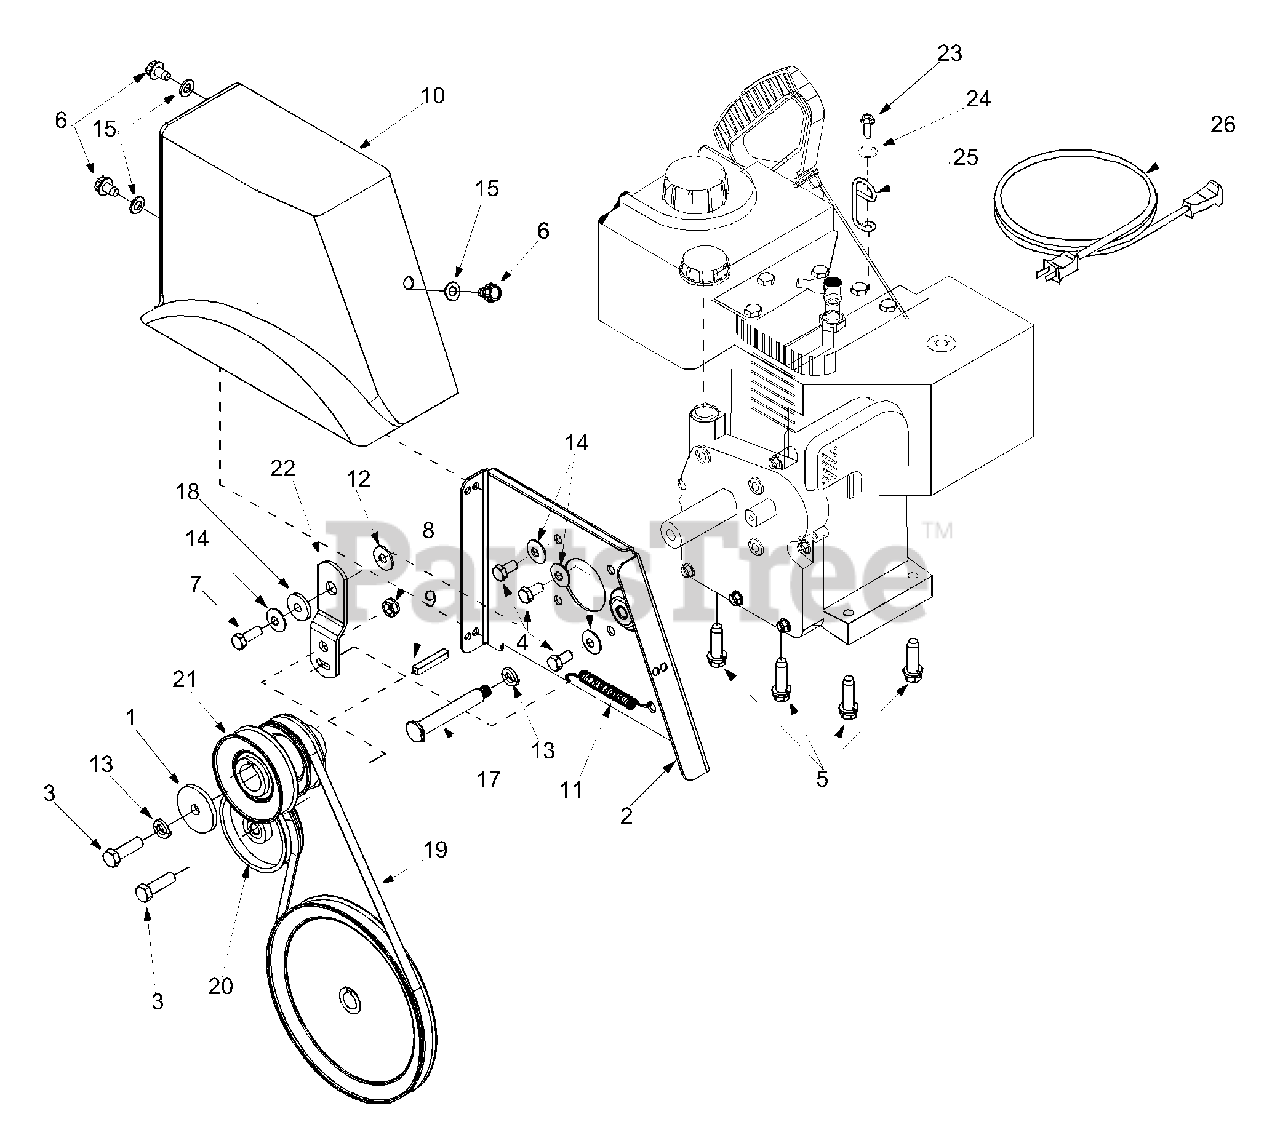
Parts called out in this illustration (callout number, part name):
1	Washer
2	Belt Cover Bracket Assembly
3	Hex Screw 3/8-24 x 1.25"
4	Hex Screw 5/16-24 x .625"
5	TT Sems Screw
6	TT Screw 5/16-18 x 0.5"
7	Hex Lock Screw 5/16-24 x .875"
8	Jam Nut
10	Belt Cover
11	Extension Spring
12	5/16 Washer
13	Lock Washer
14	Beleville Washer
15	Flat Washer
17	Shoulder Screw
18	Shoulder Spacer
19	V-Belt
20	Flat Idler
21	Double Pulley
22	Idler Bracket
23	Hex Lock Nut: 1/4-20
24	Cable Guide
25	Flat Washer
26	Extension Cord: 110V, 3-prong
